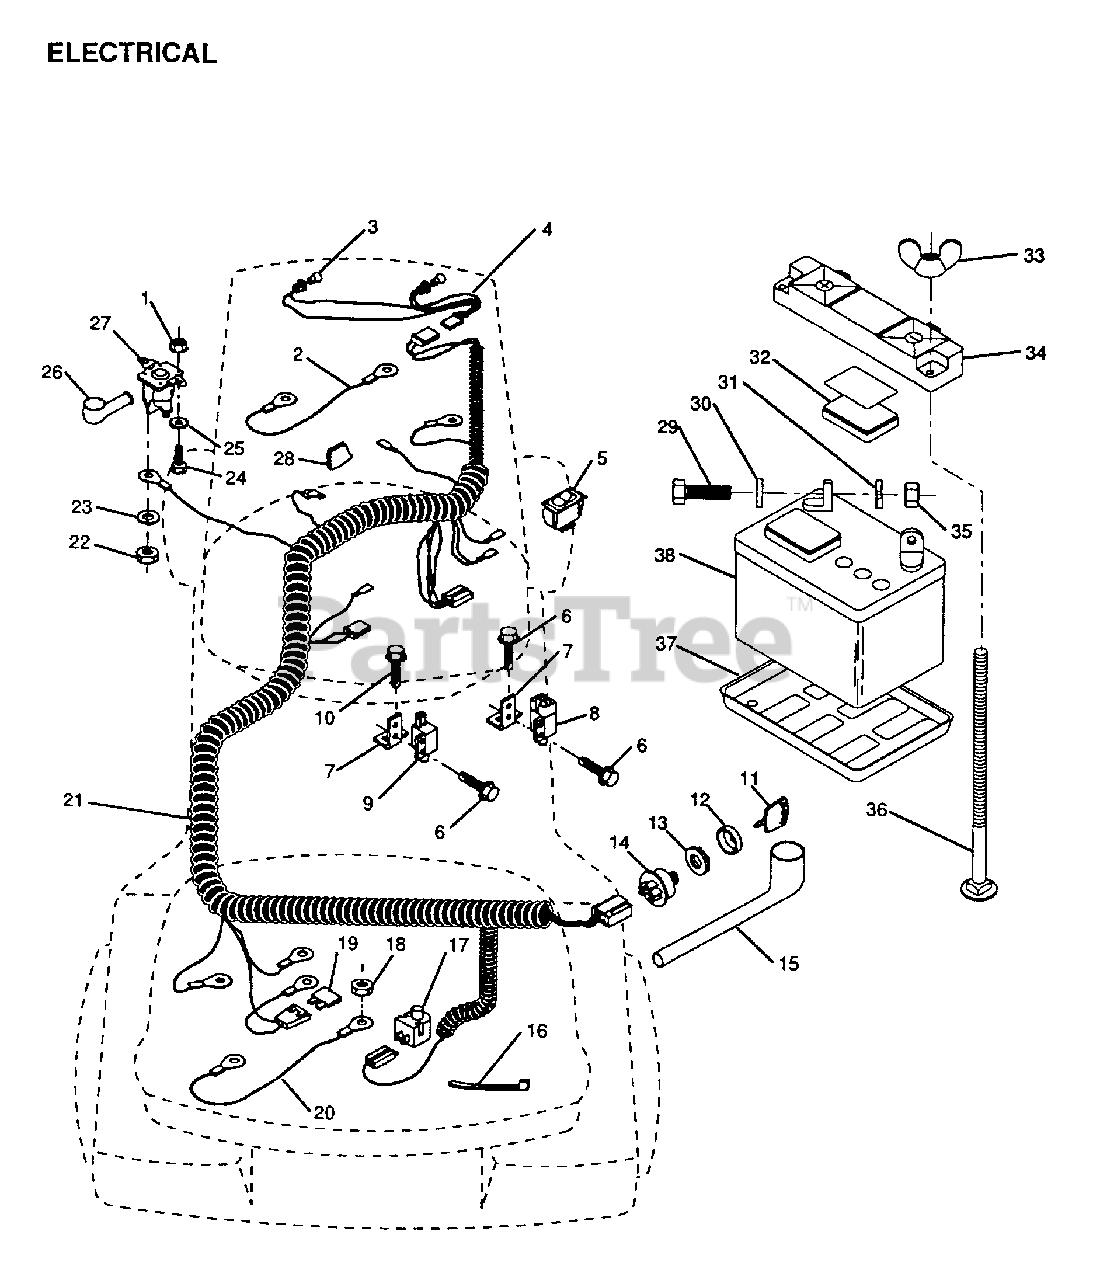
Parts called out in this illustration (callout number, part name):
1	NUT
2	CABLE LTV
4	HARNESS T
5	SWITCH LT
6	SCREW
7	BRACKET LT
8	SWITCH-INTER. GT
9	SWITCH INTERLOCKT
10	SCREW
11	KEY
13	NUT IGNITION
15	COVER IGNITION SW
16	WIRE TIE
17	SWITCH SEAT
19	FUSE HYT
21	HARNESS IGNITION
22	NUT
24	BOLT
28	STOP PLASTIC
29	BOLT LT
30	WASHER
31	LOCKWASHER
32	"CAP,BATTERY "
36	BOLT
37	"TRAY T, BATTERY"
